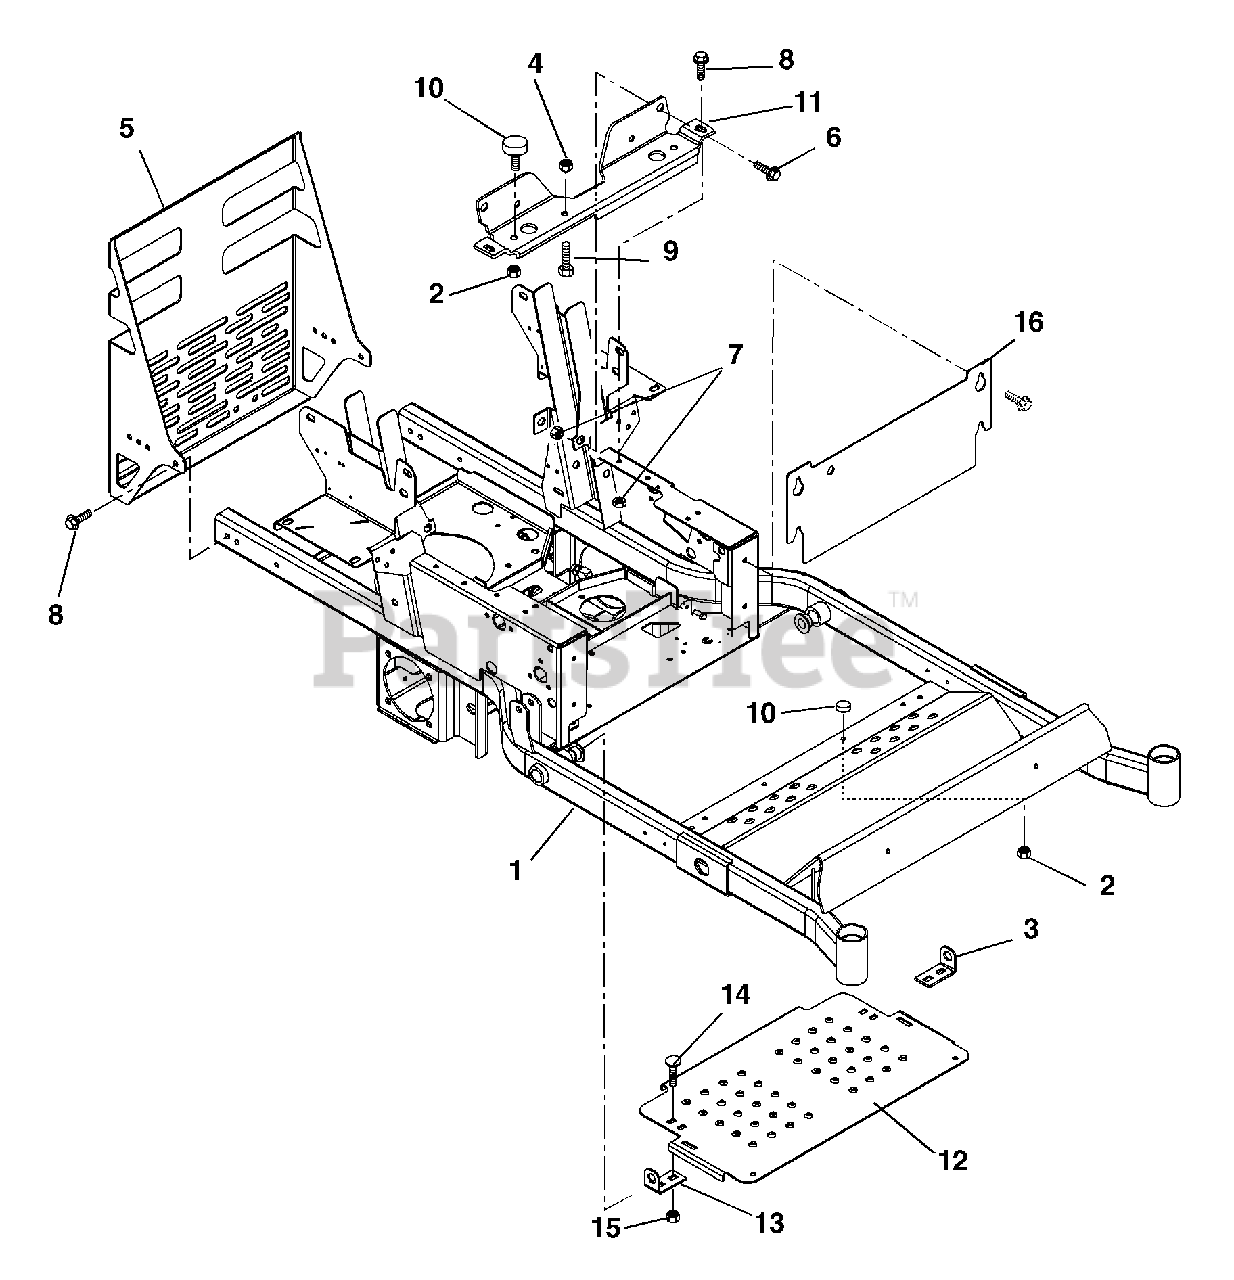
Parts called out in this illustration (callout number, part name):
1	INTERM Z FRAME 44" 48" 52"-BLK
2	@NUT-SPNLK-FLG .312-18 YWZC
3	HINGE, FOOTBOARD LH
4	@NUT-LK-TOP-FLG .31-18 YWZC
5	BUMPER/GUARD - BLACK
6	BLT-SERHFWH .375-16X1.0 YWZC
7	NUT-RTNR .375-16X.37
8	@SCR-TAP .38-16X.50 HWH TR YWZ
9	@BLT-HEX .31-18X1.25 GR5 YWZC
10	BUMPER, RUBBER
11	SEAT SUPPORT - BLACK
12	FOOTREST PANEL - 0RANGE
13	HINGE, FOOTBOARD RH
14	@BLT-RDHDSQNK .38-16X.75 G5YZ
15	@NUT-LK-TOP-FLG .38-16 YWZC
16	ACCESS PANEL - ORANGE
